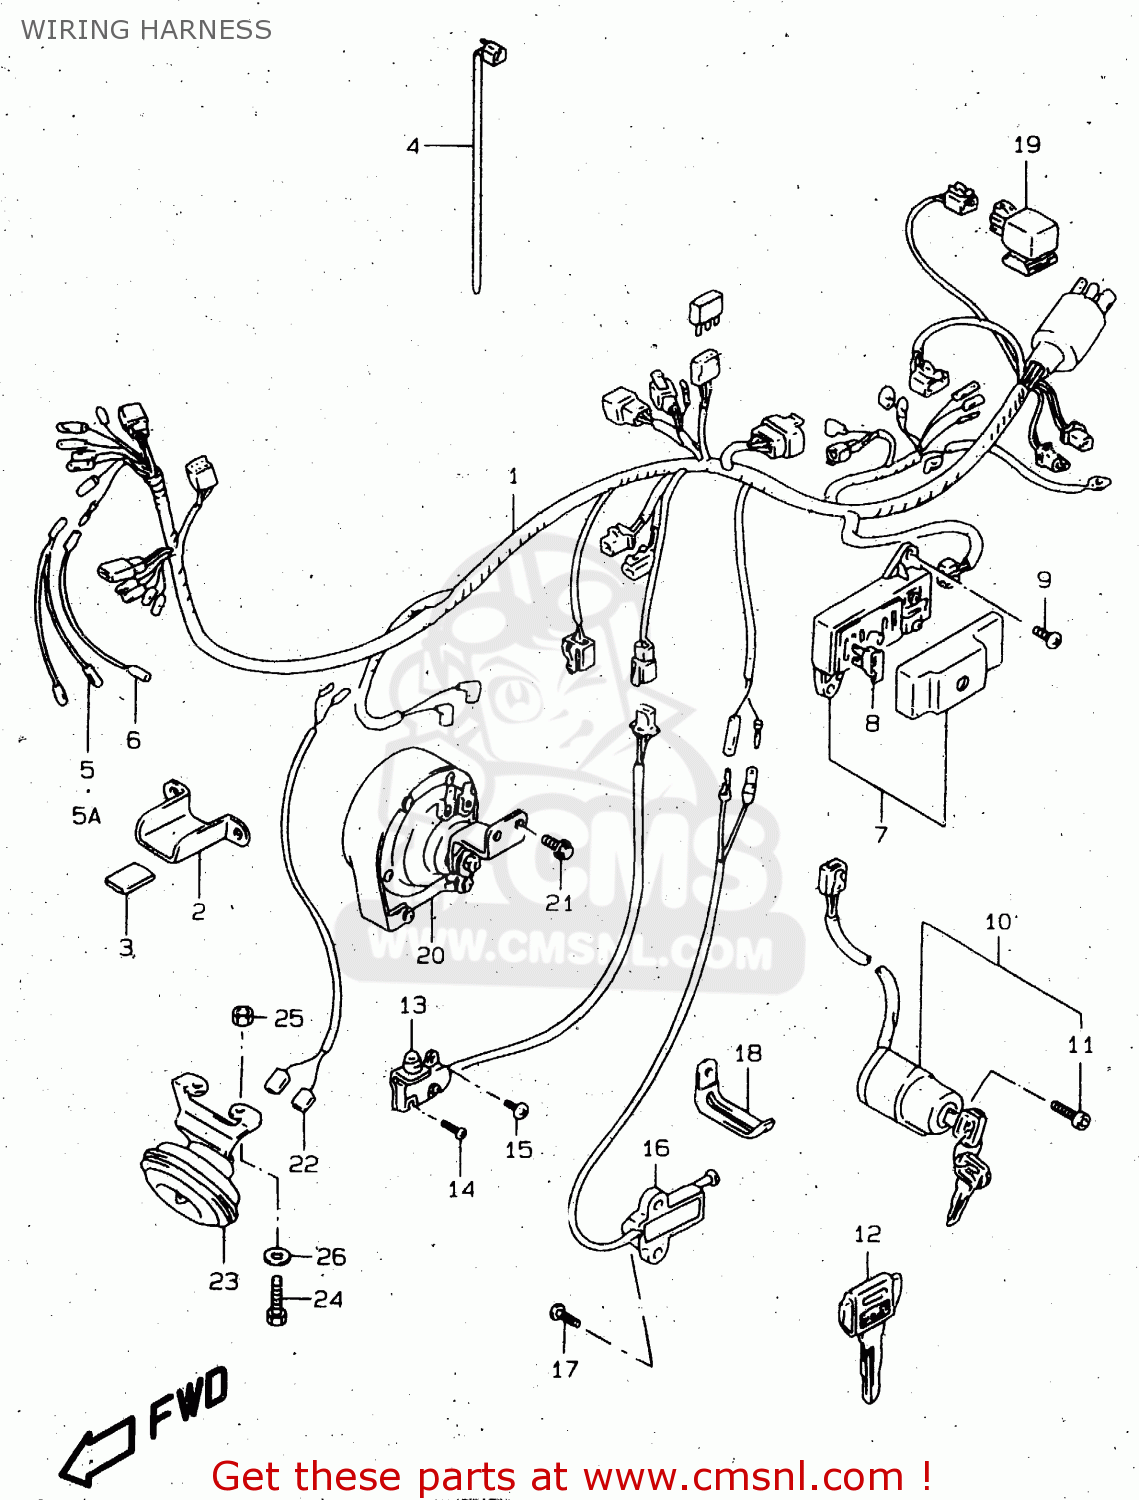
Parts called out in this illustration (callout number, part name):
1	HARNESS,WIRING
2	GUIDE,WIRING HARNESS
3	CUSHION
4	CLAMP L:165
5	WIRE,CLUTCH SW CONNECTOR
5A	WIRE,CLUTCH SW CONNECTOR
6	WIRE, LIGHTING SWITCH
7	BOX ASSY,FUSE
8	FUSE(25A)
9	SCREW
10	SWITCH ASSY,IGNITION
11	BOLT
12	KEY,BLANK(TYPE:C)
13	SWITCH ASSY,STOP LAMP
14	SCREW 4X16
15	SCREW
16	SWITCH ASSY,SIDE STAND
17	SCREW
18	CLAMP(L:65)
19	RELAY ASSY
20	HORN ASSY
21	BOLT
22	WIRE,HORN LEAD
23	HORN ASSY
24	BOLT
25	NUT 6MM
26	WASHER
